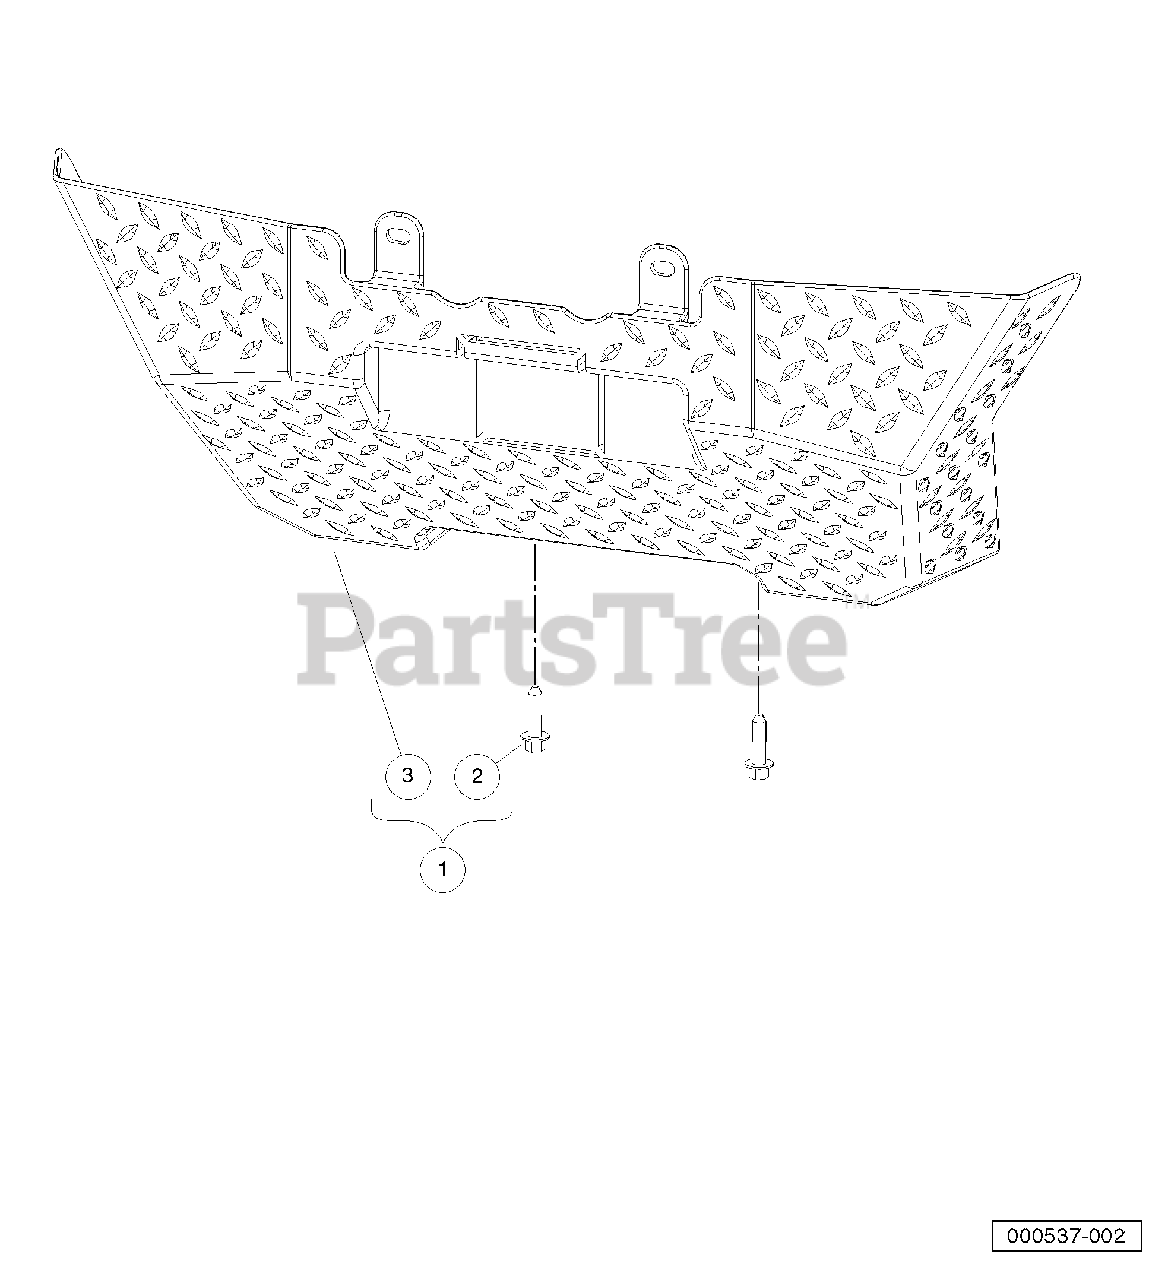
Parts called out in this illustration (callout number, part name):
1	Instl, Skid, Std
2	Screw, M8X1.25X30, Hex
3	Plate, Skid, Std
